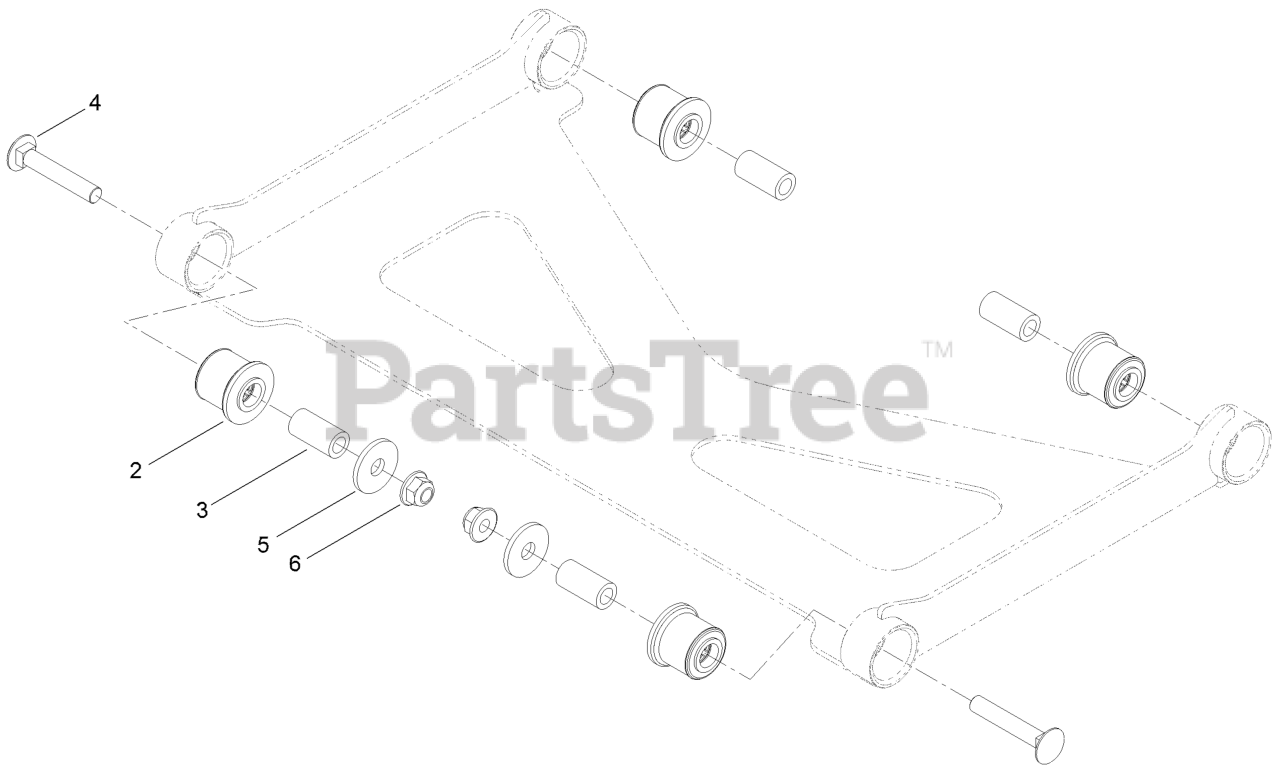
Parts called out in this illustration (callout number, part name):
2	BUSHING-RUBBER, SUSPENSION
4	Bolt-Carriage 3/8-16 X 2 1/4
5	WASHER
6	NUT-HF, NI
